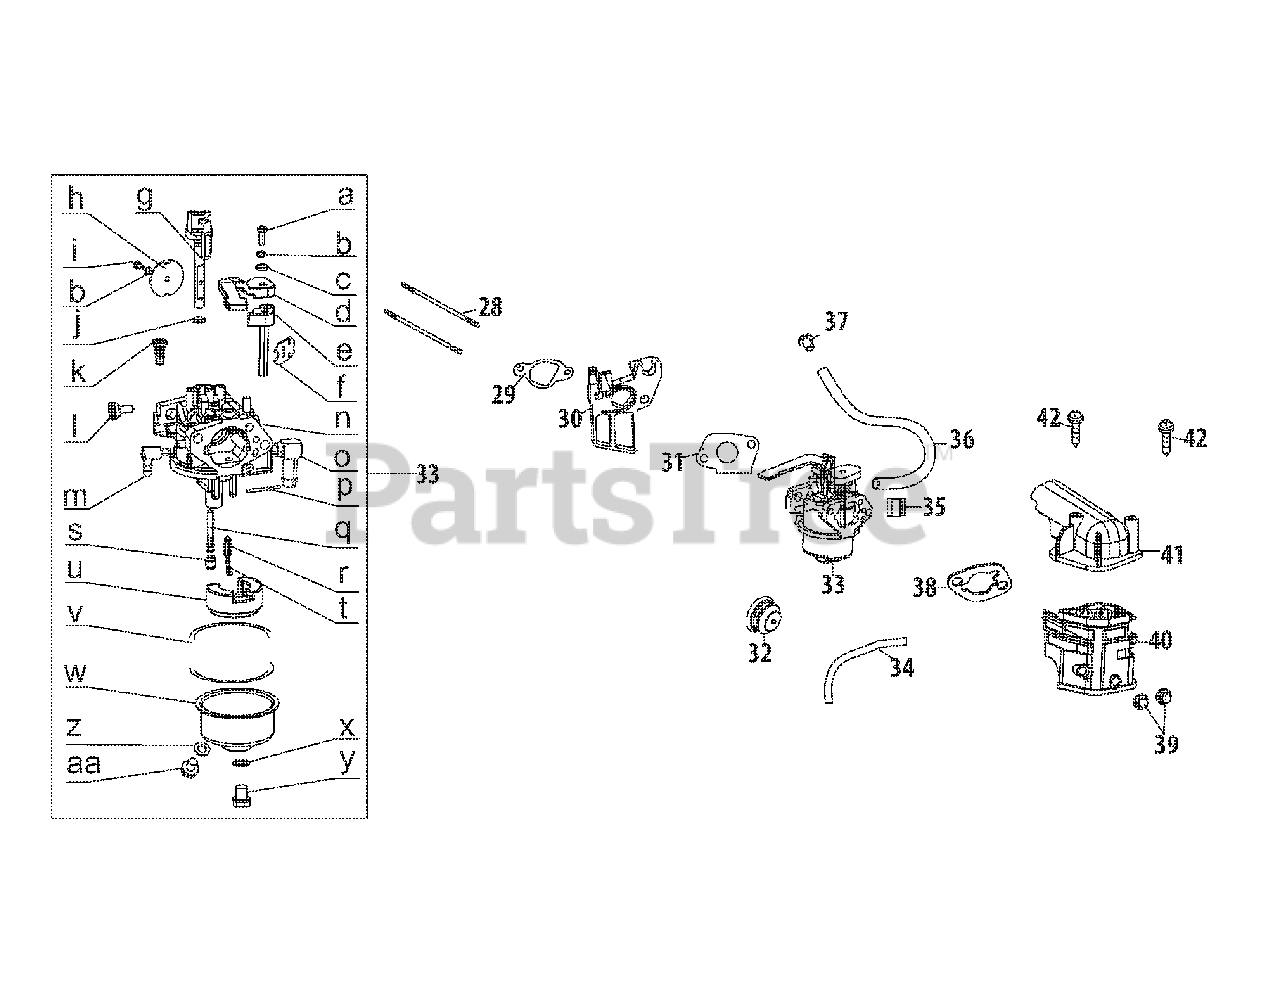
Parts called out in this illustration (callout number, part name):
28	Stud M6×113
29	Gasket, Carburetor Insulator
30	Carburetor Insulator
31	Carburetor Gasket
33	Carburetor
34	Primer Hose 3.2×6.5×530
35	Clamp, Fuel Hose
36	Fuel Hose 6.3×12.5×300
38	Carburetor Gasket Plate
39	Flange Nut M6
40	Air Filter Base
41	Heater Box
42	Screw 4.2×45
